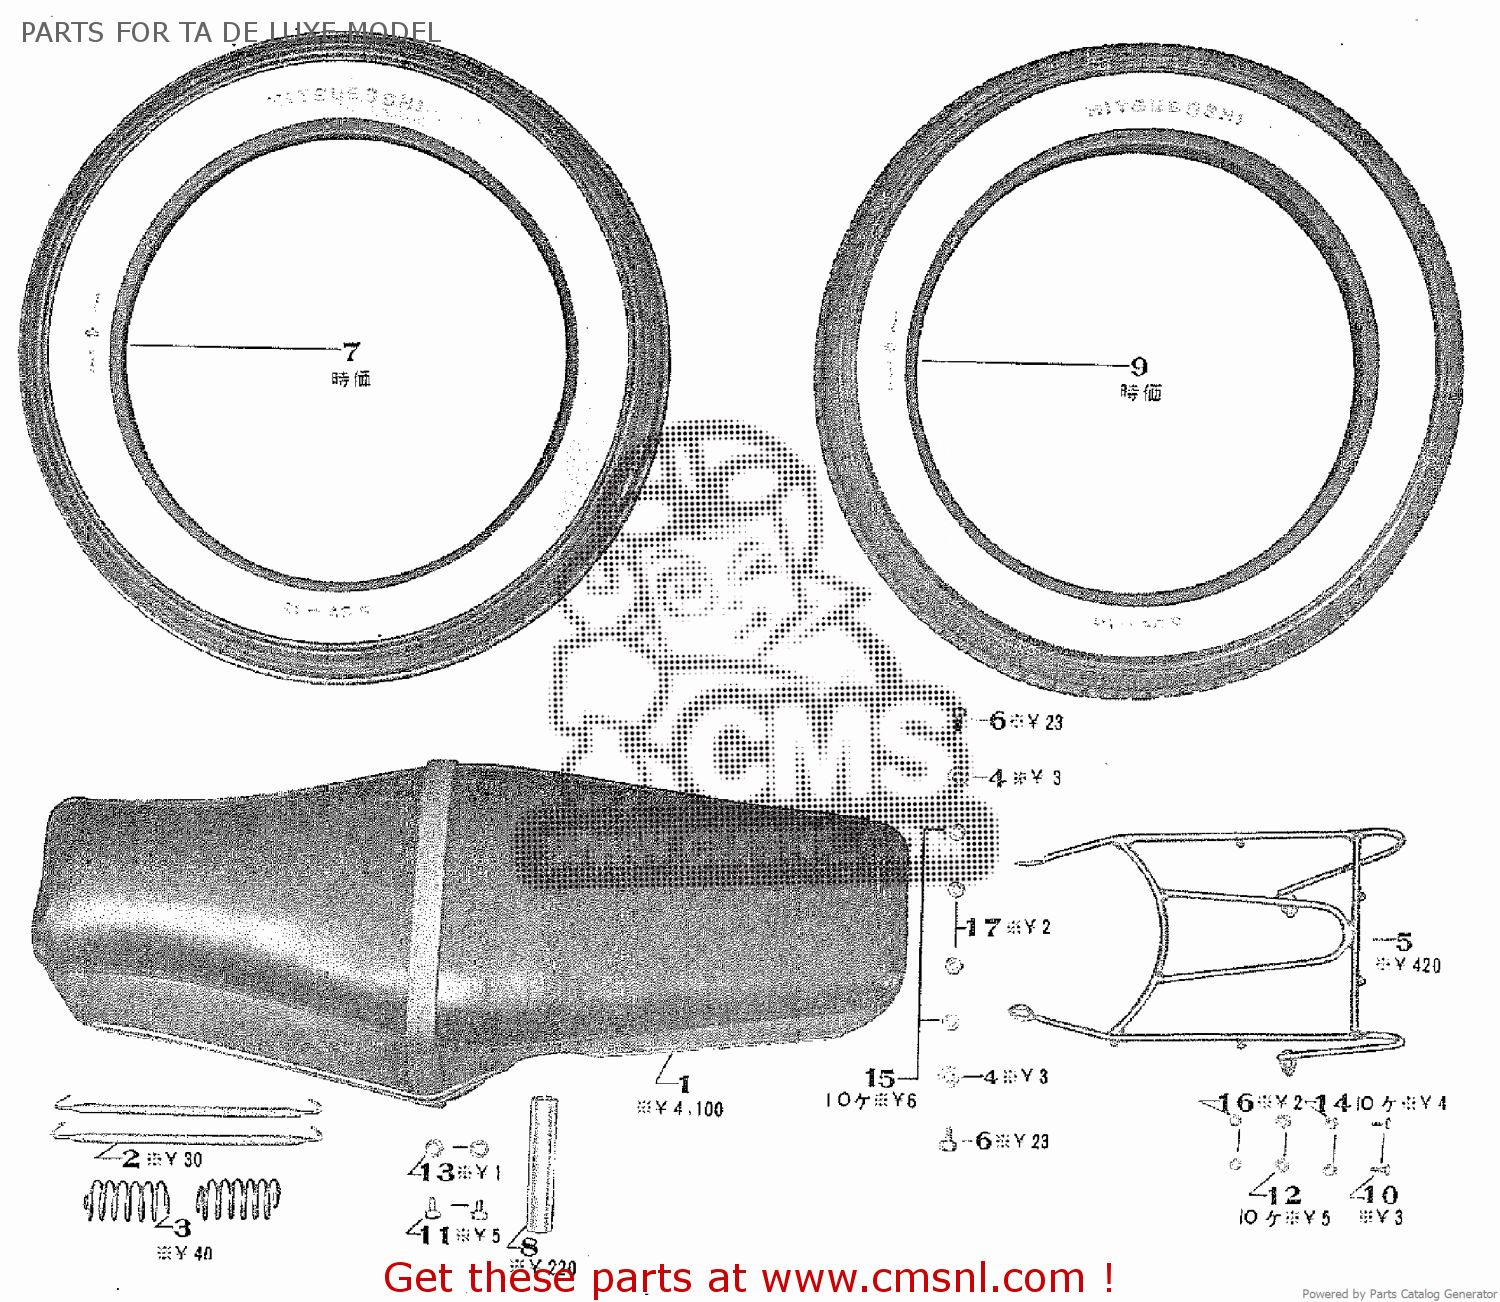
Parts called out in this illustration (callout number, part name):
1	DUAL SEAT ASSY.
2	TENSION SPRING
3	DUAL SEAT SPRING
4	SET WASHER
5	SUB CARRIER COMP.
6	SUB CARRIER UPPER SET BOLT
7	FRONT TIRE
8	UPPER DISTANCE COLLAR
9	REAR TIRE
10	6X15 HEXAGON BOLT
11	8X12 HEXAGON BOLT
12	6MM PLANE WASHER
13	8MM PLANE WASHER
14	6MM SPRING WASHER
15	8MM SPRING WASHER
16	6MM HEXAGON NUT
17	8MM HEXAGON NUT
